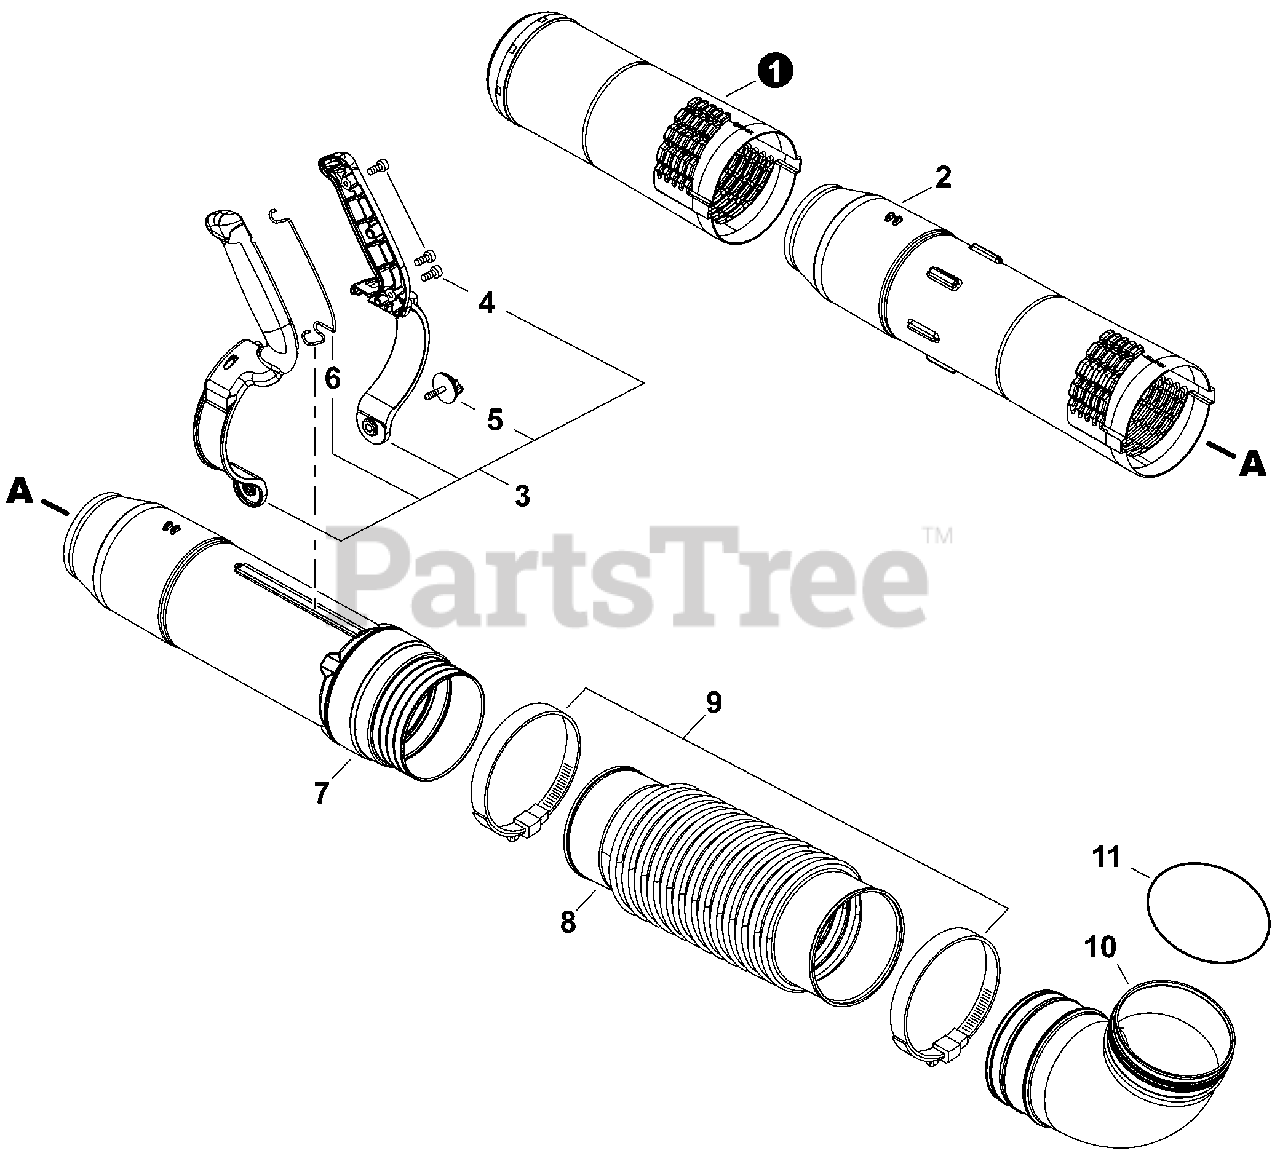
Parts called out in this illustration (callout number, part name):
1	TUBE, BLOWER - NOZZLE
2	TUBE, BLOWER - STRAIGHT
3	HANDLE KIT - BLOWER TUBE
4	BOLT, TORX 4x12
5	KNOB, FASTENER
6	PLATE, GROUND
7	TUBE, BLOWER - SWIVEL
8	TUBE, BLOWER - FLEXIBLE
9	CLAMP - BAND
10	TUBE, BLOWER - ELBOW
